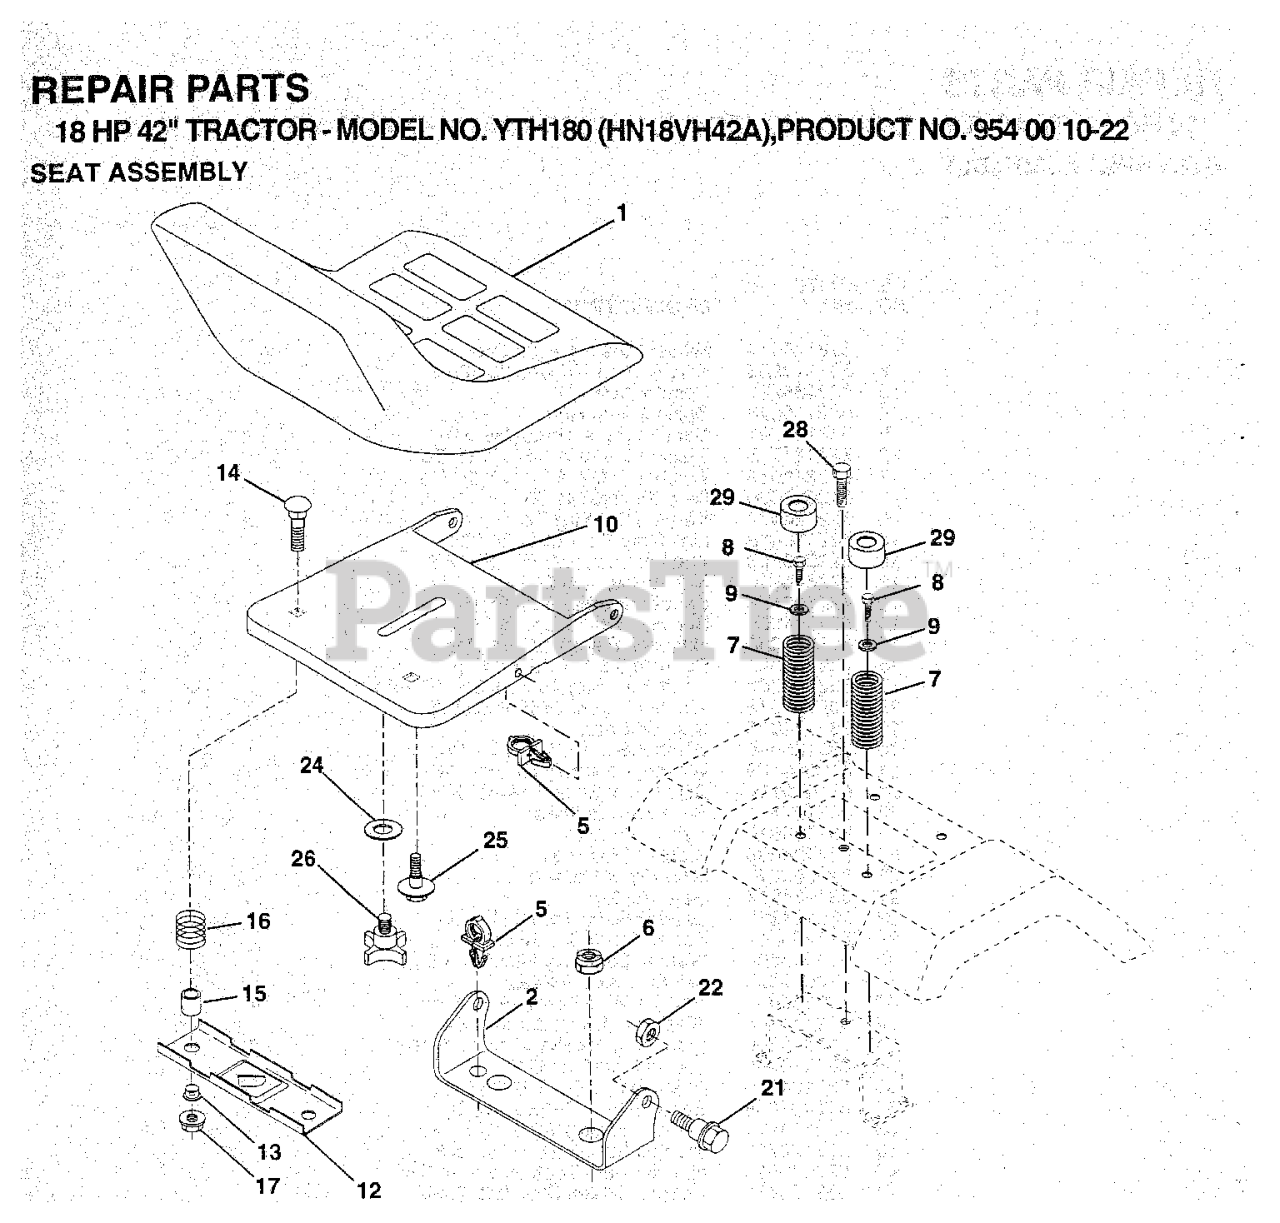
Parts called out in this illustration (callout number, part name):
1	SEAT
2	SEAT PIVOT BRKT
5	INSULATED CLIP
6	NUT
7	SPRING COMPRESSION
8	Screw 5/16-18 x 1/2 Hex, Self Tapping 5/16-18 x 1/2
9	WASHER
10	SEAT PAN
12	BRKT SWITCH
14	Bolt Rdhd. Sht. Nk 1/4-20 x 1-3/8
15	SPACER SPLIT
16	SPRING COMPRESSED
17	NUT T
21	BOLT.SHOULDER.5/16-18
22	LOCKNUT
25	BOLT,SHOULD
26	KNOB 1/2" YT
29	CAP SPRING
